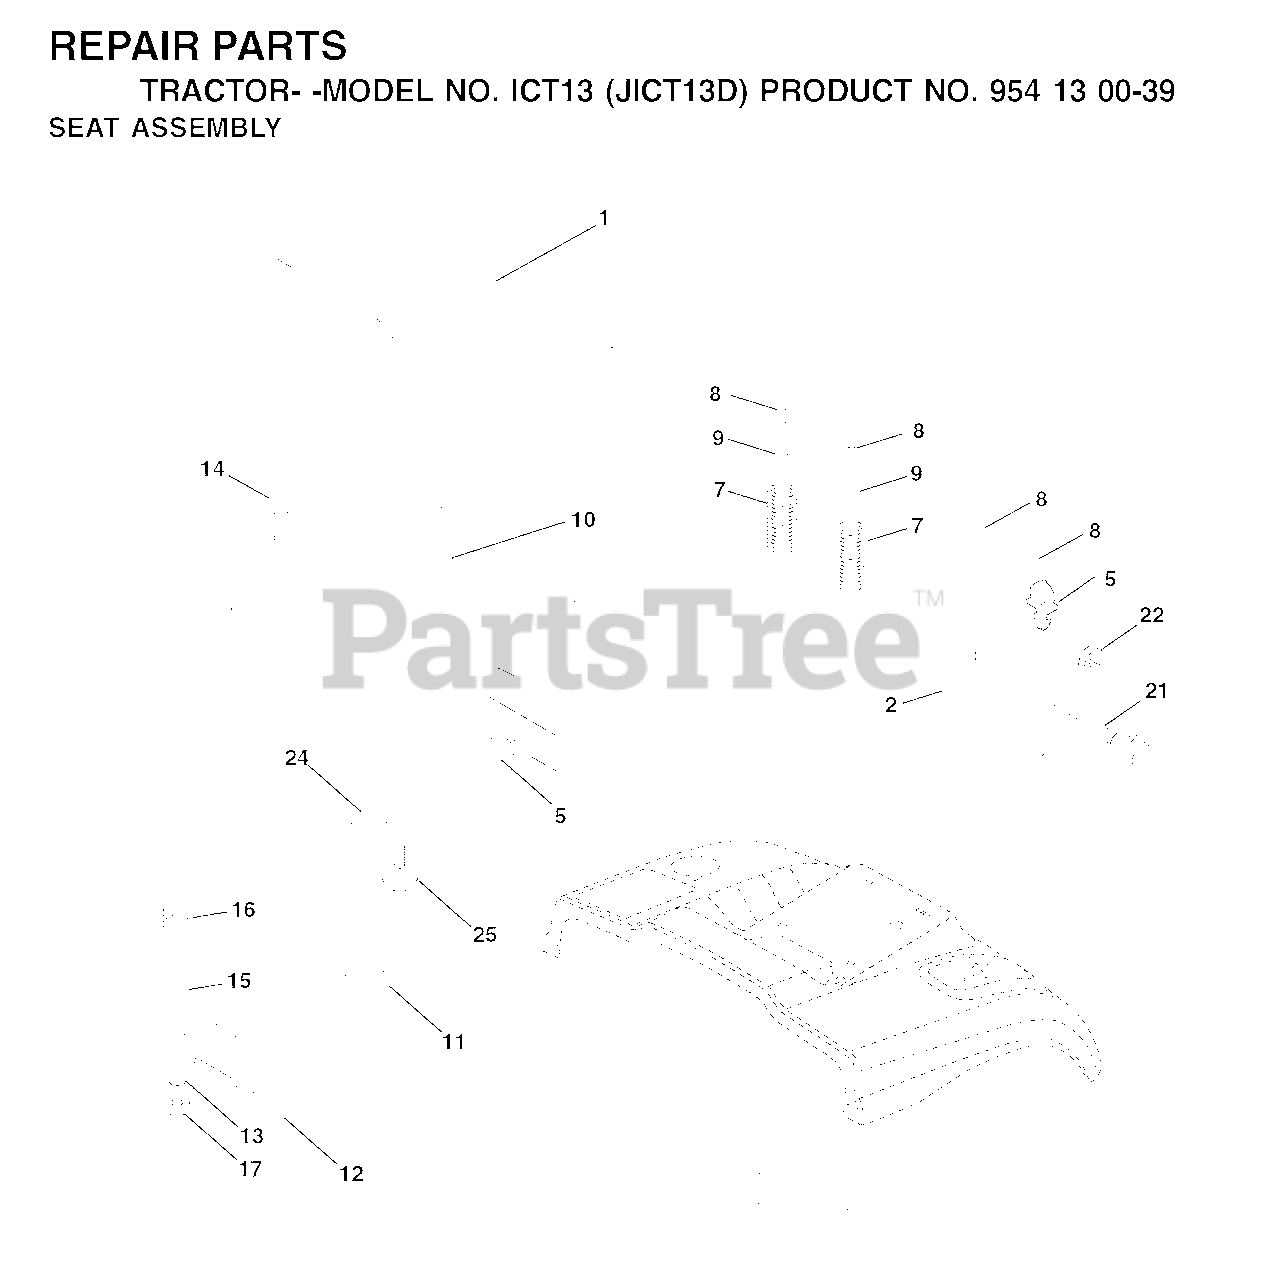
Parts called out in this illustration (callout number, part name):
2	SEAT PIVOT BRKT
5	PUSH CLIP
7	SPRING COMPRESSION
8	SCREW 3/8-16X1
9	WASHER
10	PAN, SEAT
11	KNOB.SEAT.ADJ.WINGNUT
12	BRKT SWITCH
14	BOLT.ROUND.HEAD.SQUARE.NECK
15	SPACER SPLIT 28X.96
17	NUT T
21	BOLT.SHOULDER.5/16-18
22	NUT.71038.31-18.HEX.NYLOCK
25	BOLT,SHOULD
